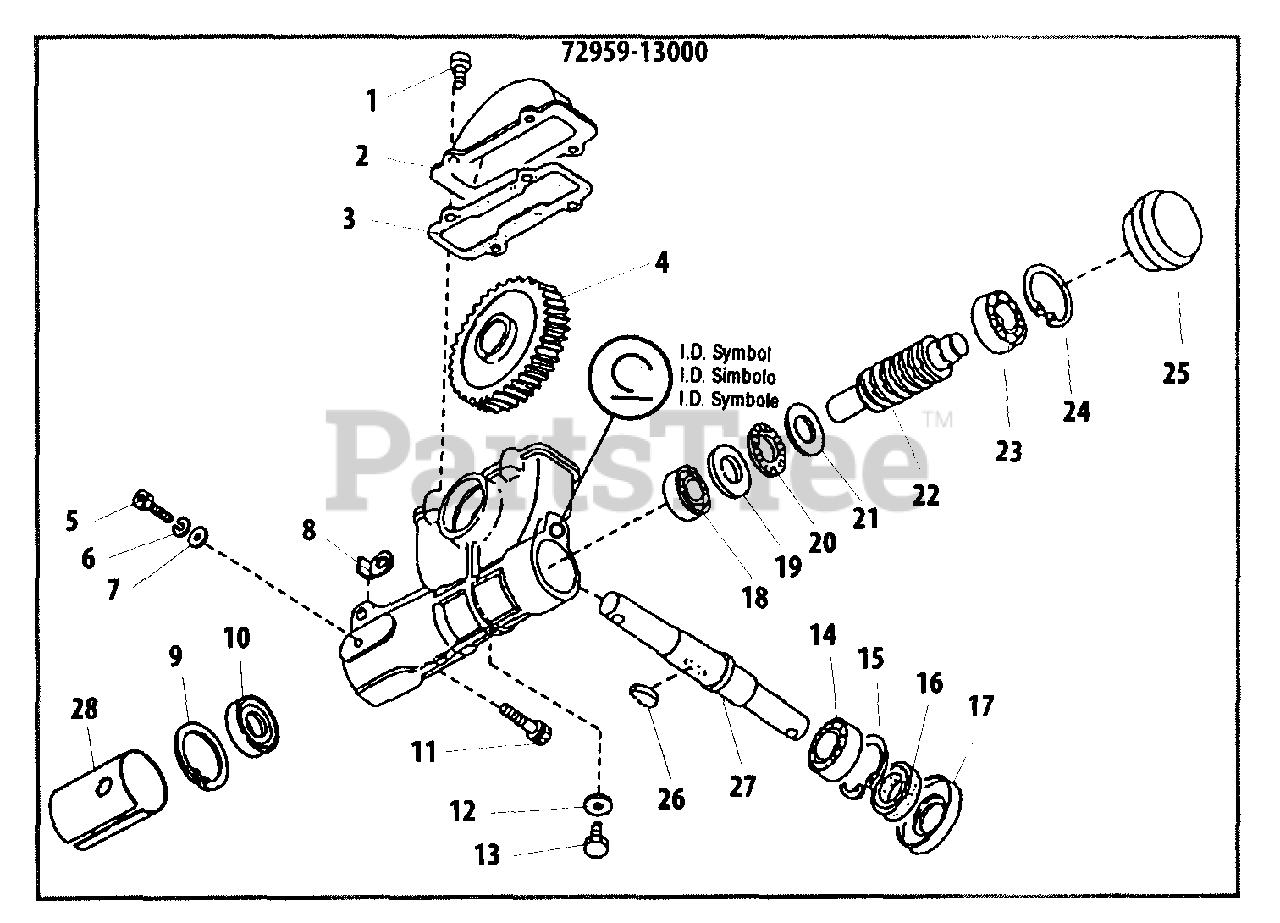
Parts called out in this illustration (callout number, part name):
1	SCREW
2	COVER, GEAR CASE
3	GASKET
4	GEAR, WORM
5	BOLT 5×12
6	WASHER, SPRING 5
7	WASHER, FLAT 5.5×10×0.8
9	RING, SNAP Ø22
10	SEAL, OIL
11	SCREW - 6×30
14	BEARING, BALL
15	RING, SNAP Ø28
16	SEAL, OIL
18	BEARING, BALL 6901
19	WASHER, THRUST
20	BEARING, NEEDLE
21	WASHER, THRUST
22	GEAR, WORM
23	BEARING, BALL 6001
24	RING, SNAP Ø28
25	CAP
27	DRIVESHAFT
28	SPACER
72959-13000	GEAR CASE ASSY
